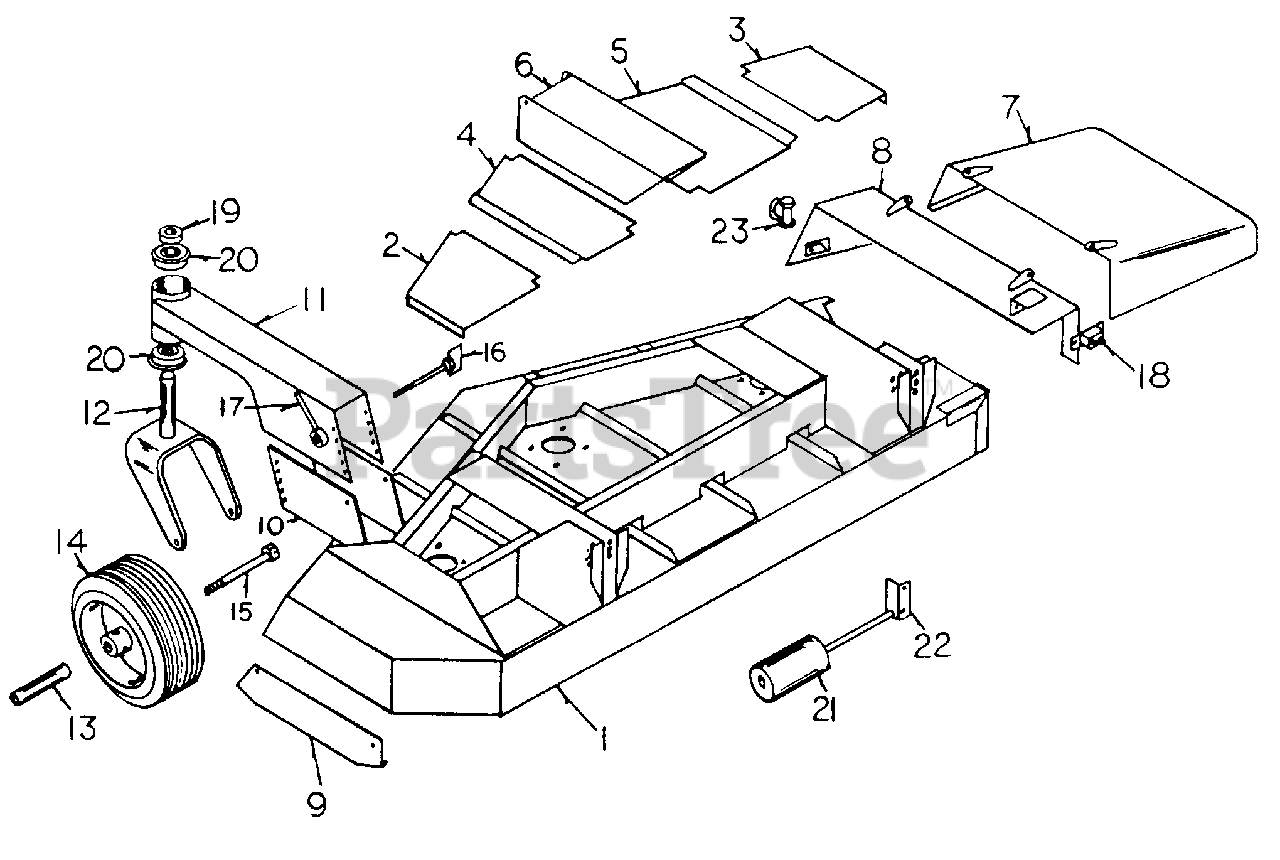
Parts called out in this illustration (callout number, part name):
1	Deck, 52"
2	Outside Cover, LH
3	Outslde Cover, RH.
4	Center Cover, LH
5	Center Cover, RH.
6	Drive Shaft Cover
7	Fas-tatch Foot Guard
8	Fas-tatch Foot Gusrd Mbunt
10	Gauge Wheel Mount Bracket
11	Gauge Wheel Mbunt
12	Gauge Wheel Fork
13	Axle
14	Wheel Assembly
15	Hex Bolt, 1/2-13 x 6 1/2"
18	10 Amp Circult Breaker
21	Antl-scalp Roller
22	Shaft & Bracket
23	LS Fas-tatch Pin
